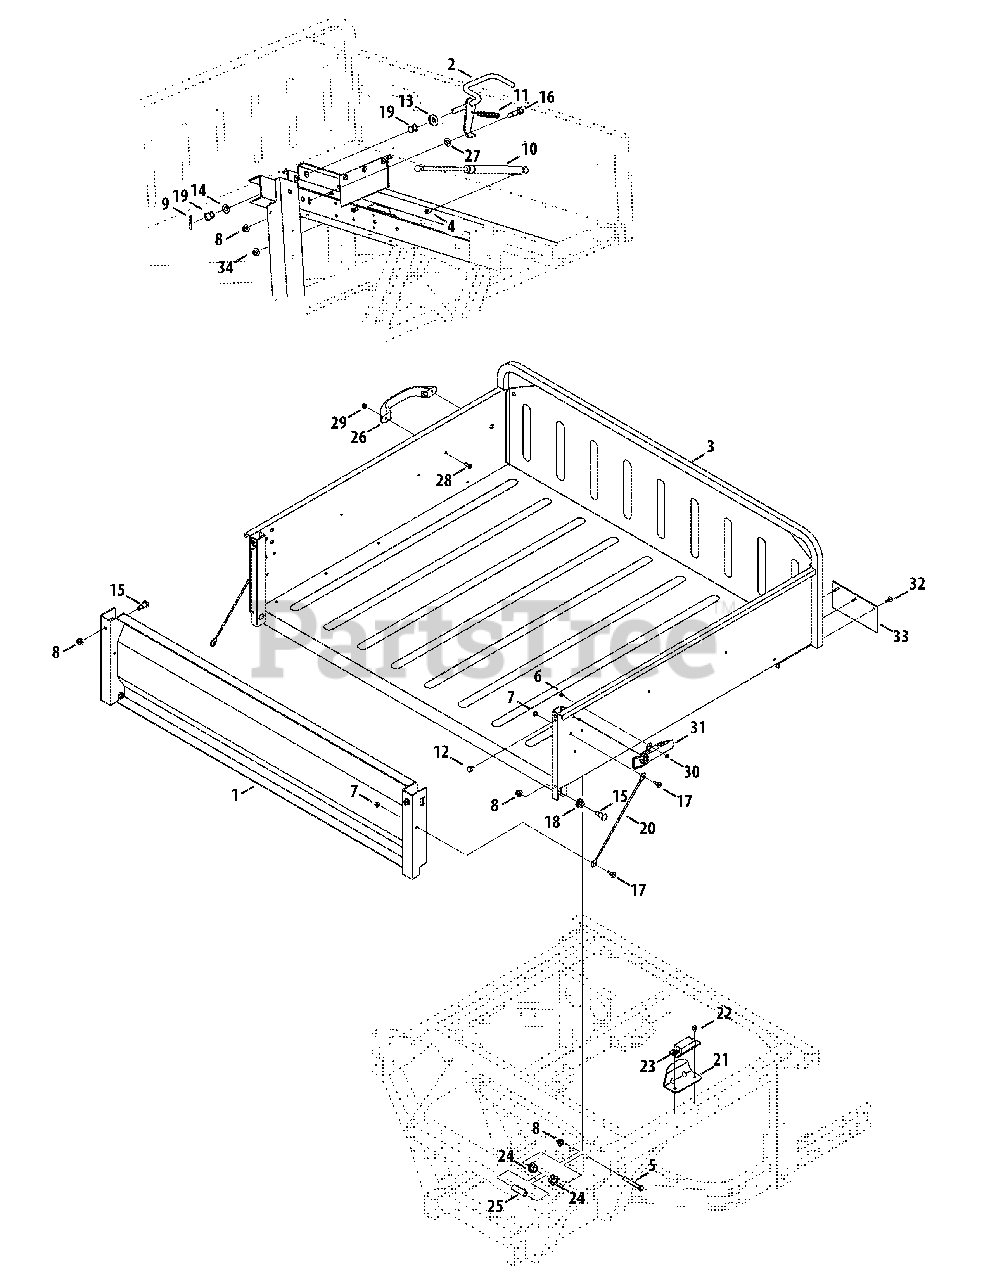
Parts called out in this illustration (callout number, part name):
1	Tailgate Assembly, Black
1	Tailgate Assembly, Cub Yellow
1	Tailgate Assembly, Green
1	Tailgate Assembly, Red
2	Lever Assembly, bed, latch
3	Box Assembly, bed Black
3	Box Assembly, bed Red
3	Box Assembly, bed Green
3	Box Assembly, bed Yellow
4	Stud, ball, 5/16-18
5	Screw, 3/8-16, 2.75, gr5, std
6	Screw, machine, 10-24, 0.500
7	Nut, Flange Lock, 1/4-20, nylon
8	Nut, Flange Lock, 3/8-16, nylon
9	Pin, cotter, 5/32, 1.25
10	Spring, gas, 6.91 Stroke
11	Spring, extension, .50 Od x 4.35
12	Bumper, .62 Dia. x .3
13	Washer, flat, .531 x 1.25 x .181
14	Washer, flat, .510 x 1.00 x .060
15	Screw, shoulder, .50 x .685, 3/8-16
16	Screw, shoulder, .50x.925, 3/8-16
17	Screw, shoulder, .375x.280, 1/4-20
18	Bearing, Flange, hex, .506 Id x .590
19	Bearing, Flange, .503 x .689 x .792
20	Cable, lanyard
21	Bracket, Bed Guide
22	Screw, tt, 1/4-20x.625, hxindwsh
23	Bumper, suspension, extension
24	Bearing, hex Flange .629 Id
25	Spacer, .390 Id x.625 Od x2.03 Lg
27	Washer, Flat, .385 x .870 x .092
28	Screw, Mach., 1/4-20 x .750
29	Nut, Hex Lock., 1/4-20
30	Nut, Hex lock, #10-24, gr2, nylon
31	Latch, draw, over Center
32	Pop Rivet, .188 dia, 37-50 grip
33	Rear Mud Flap
34	Nut, Flange Lock, 5/16-18, nylon
